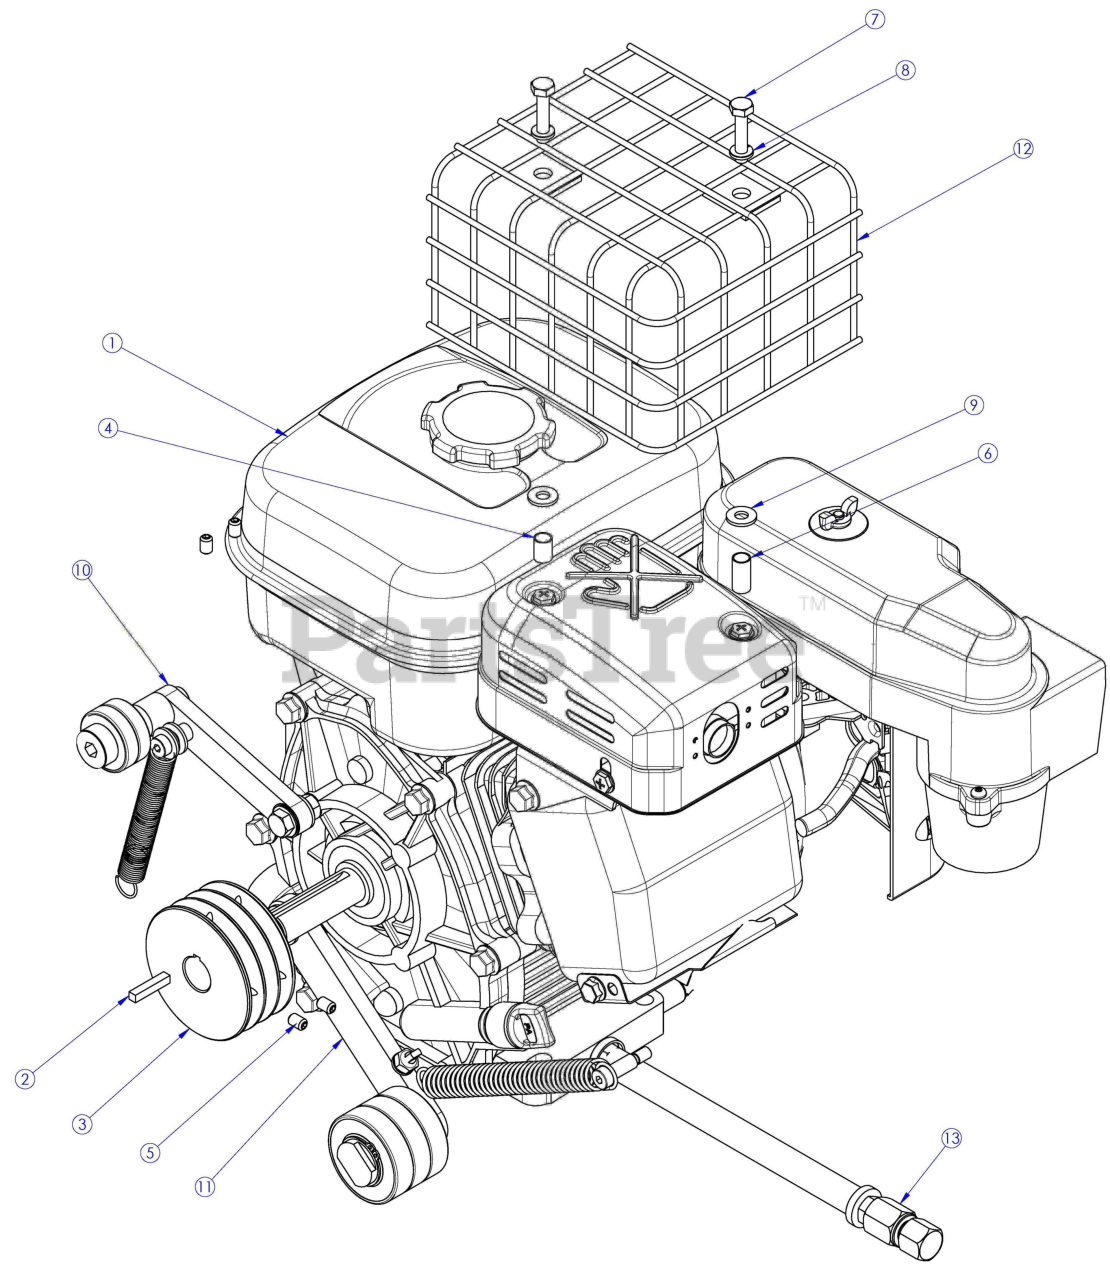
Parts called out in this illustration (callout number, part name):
1	Engine 6Hp
2	Key, 3/16 X 3/16 X 1.00
3	Sheave, 3/3V 3.00 Od X .750 Id
4	Spacer, .313" Id X .500" L
5	Set Screw, Knurled .250-20 X .375
6	Spacer, .313"Id X .770"L
7	HHB 1/4-20 X 1.25 Gr8
8	Washer, Split 1/4" S.S.
9	Washer, 1/4" Flat S.S.
10	Pump Idler Assembly
11	Blade Idler Assembly
12	Muffler Guard, X750
13	Kit, Oil Drain
